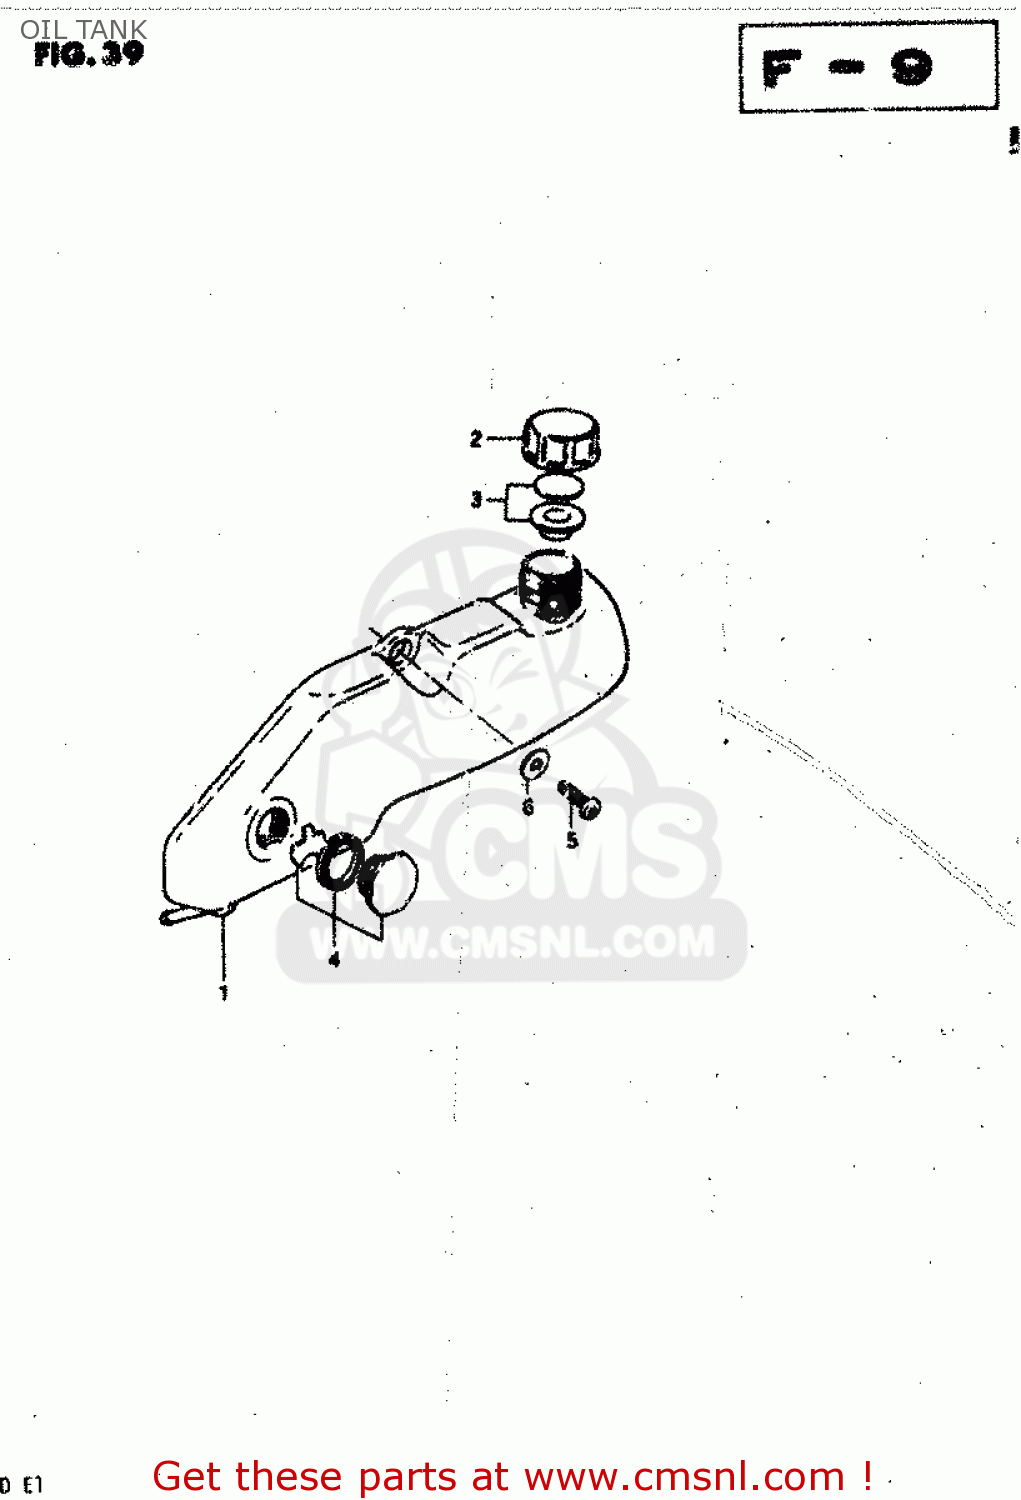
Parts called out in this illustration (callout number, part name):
1	TANK, OIL
2	CAP,OIL TANK
3	GASKET SET (NAS)
4	LENS SET,OIL LEVEL
5	GASKET (NAS)
6	SCREW
7	WASHER
